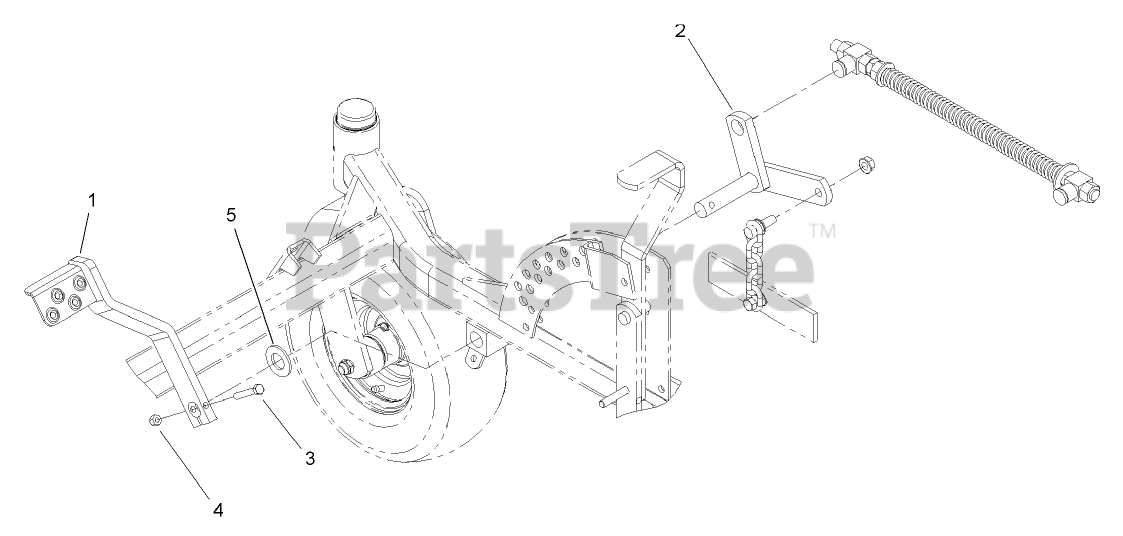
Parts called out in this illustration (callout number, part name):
1	Lever-Lift, Foot Assist
2	Lift-Foot
3	SCREW-HH
4	NUT-LOCK, NI
5	WASHER-FLAT
